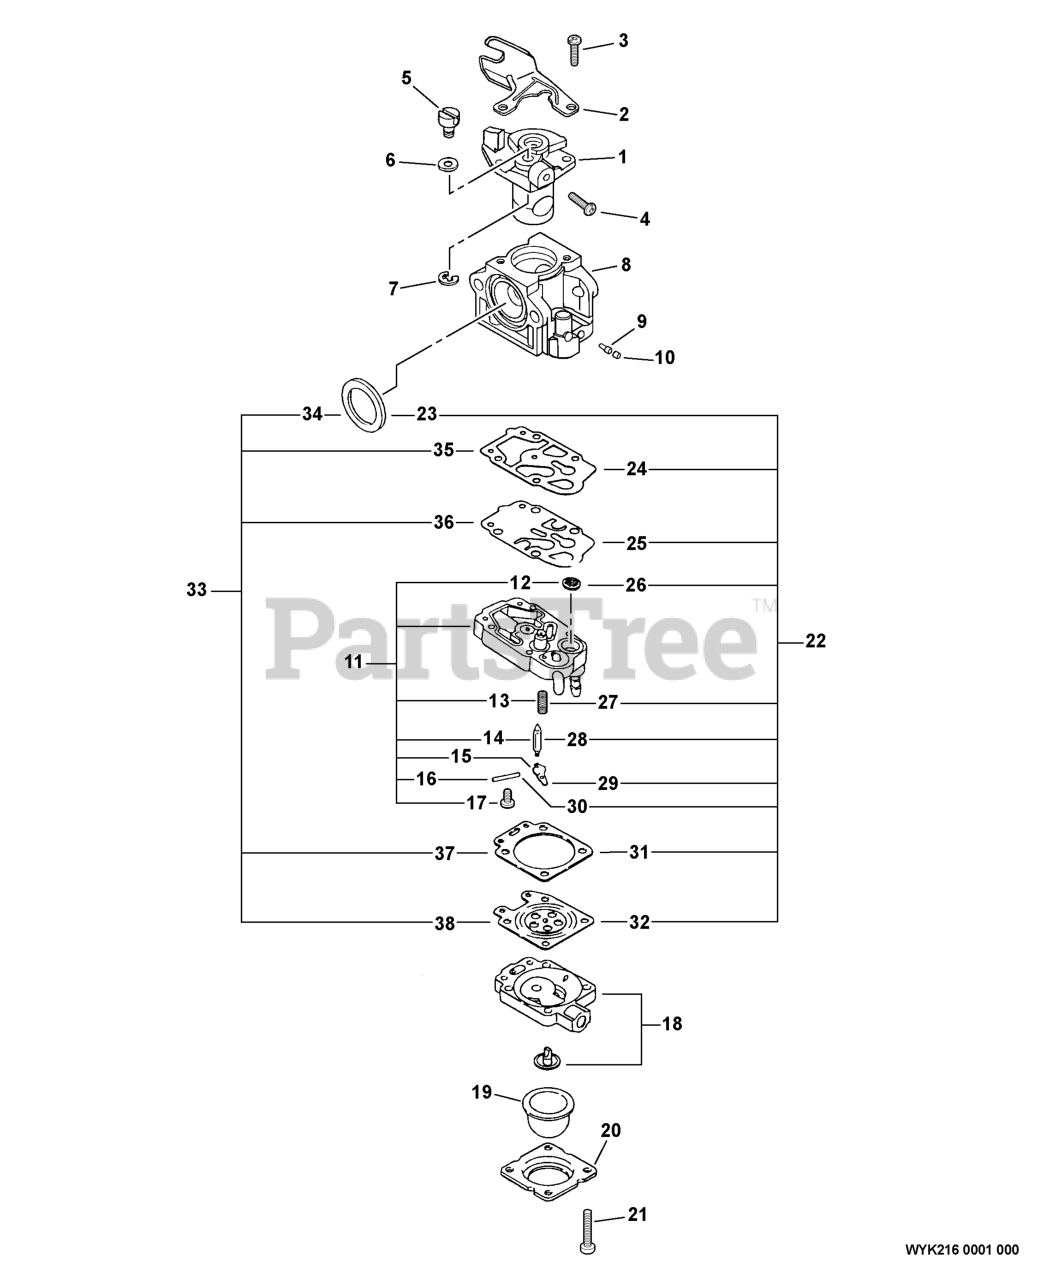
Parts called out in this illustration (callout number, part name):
1	THROTTLE VALVE ASSY
2	BRACKET, CABLE
4	SCREW, IDLE ADJUST
7	RING, RETAINING
8	BODY, CARBURETOR
9	NEEDLE - HIGH SPEED
10	CAP, LIMITER
11	PUMP BODY ASSY
12	STRAINER
13	SPRING, METERING LEVER
14	VALVE, INLET NEEDLE
15	LEVER, METERING
16	PIN, METERING LEVER
17	SCREW, METERING LEVER PIN
18	PURGE BASE ASSY
19	BULB, PURGE
20	RETAINER, PURGE BULB
21	SCREW, PUMP COVER
22	REPAIR KIT
23	SEAL
24	GASKET, PUMP
25	DIAPHRAGM, PUMP
26	STRAINER
27	SPRING, METERING LEVER
28	VALVE, INLET NEEDLE
29	LEVER, METERING
30	PIN, METERING LEVER
31	GASKET, DIAPHRAGM
32	DIAPHRAGM, METERING
33	DIAPHRAGM/GASKET KIT
34	SEAL
35	GASKET, PUMP
36	DIAPHRAGM, PUMP
37	GASKET, DIAPHRAGM
38	DIAPHRAGM, METERING
